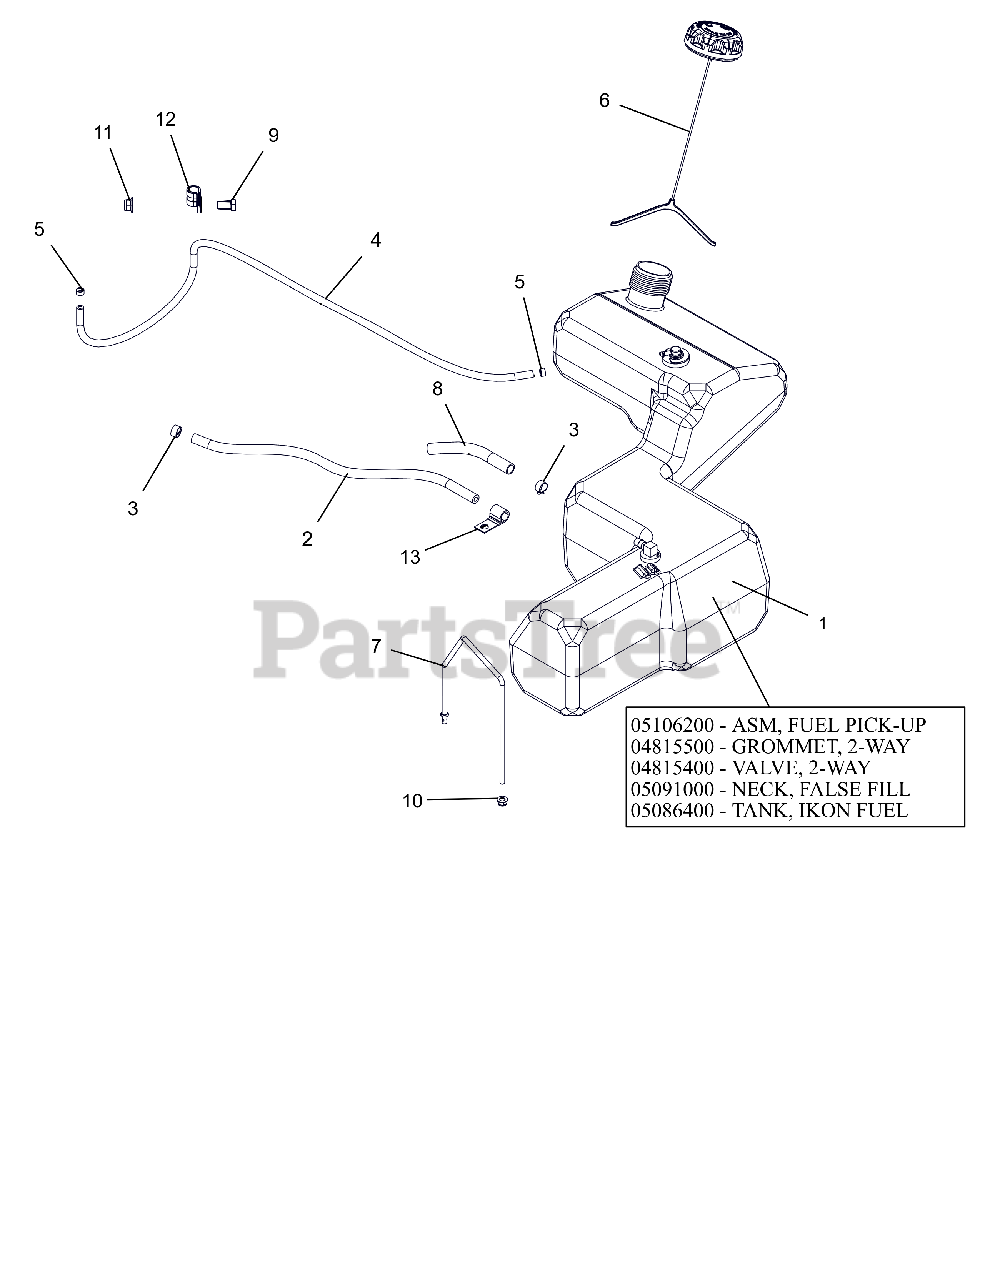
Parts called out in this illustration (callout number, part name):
1	ASSEMBLY, FUEL TANK IKON(2017)
1	ASM, IKON FUEL PICK-UP
1	GROMMET, 2-WAY
1	VALVE, 2-WAY
1	NECK, FALSE FILL-2017 IKON
1	TANK, IKON FUEL (2017)
2	HOSE, .25 LOW-PERM BULK GAS
3	CLAMP, FUEL LINE
4	HOSE, .188 LOW-PERM BULK GAS
5	CLAMP-HOSE, SPRING .188
6	CAP, FUEL VENT-IN 2.25" RATCH.
7	BRKT, FUEL TANK HOLD DOWN
8	WRAP, ANTIABRASION .5X.064WALL
9	@BLT-HEX .38-16X.75 GR5 YWZC
10	@NUT-LK-NYL-FLG .25-20 YWZC
11	@NUT-LK-NYL-FLG .38-16 YWZC
12	CLAMP, CUSHIONED STEEL
13	J-CLAMP
